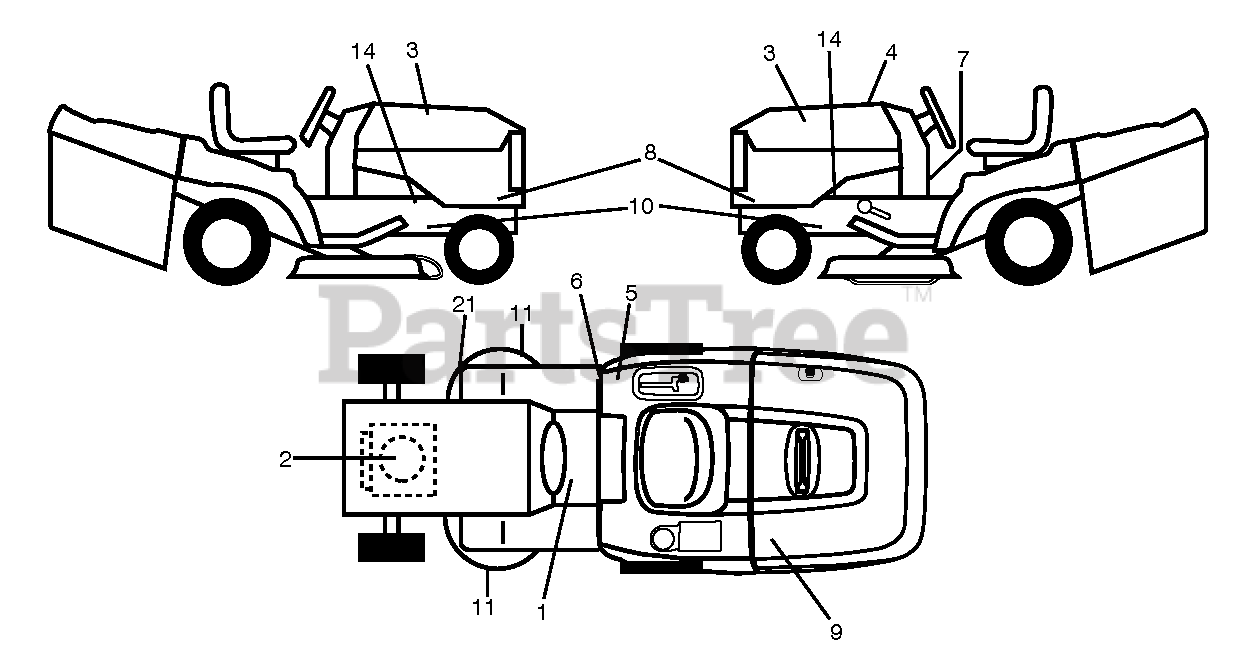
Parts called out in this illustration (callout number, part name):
2	DECAL
3	RP.DECAL.BADGE.170MM.TEXTLOGO
5	DECAL
6	Decal, Fender 100 DB/CE
11	DECAL.INTERNATIONL.CUTFINGER
21	DECAL DECAL V-BELT 97 CM CRD
